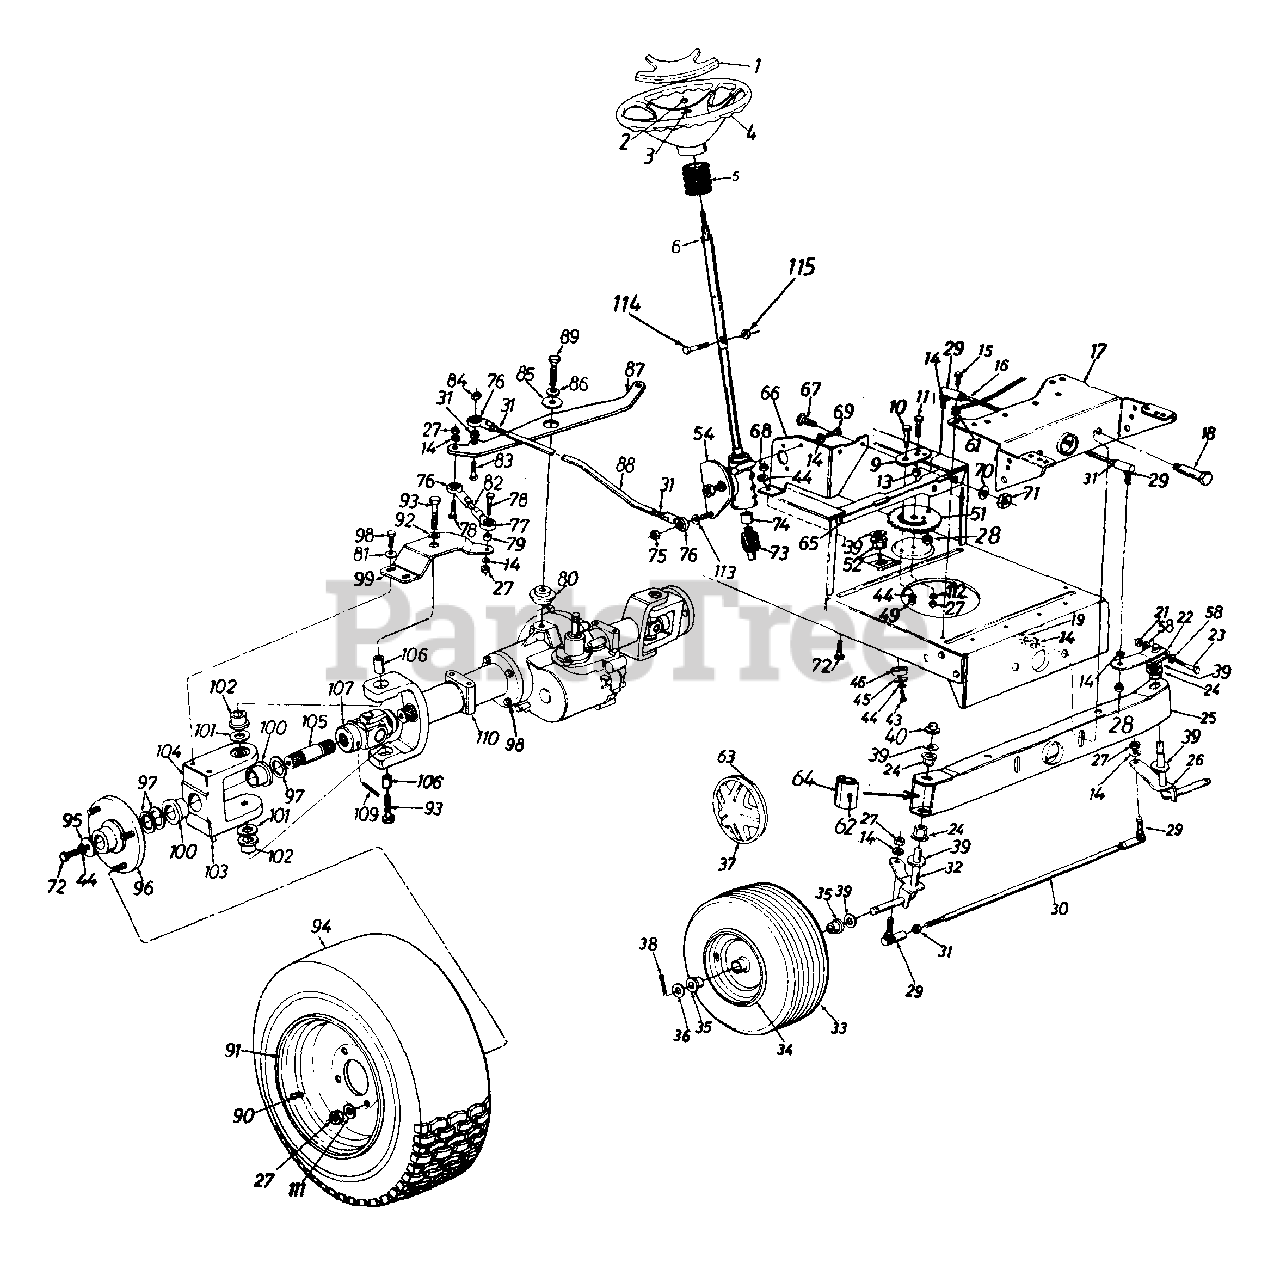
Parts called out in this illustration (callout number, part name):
1	Steering Wheel Cap
2	Hex L-Nut 5/16-24 Thd.
3	Belleville Wash. .345" I.D.
4	Steering Wheel
5	Steering Bellow
6	Upper Steering Shaft
9	Retainer Plate
10	Shoulder Bolt .437" Dia. x .35" Lg. 5/16-18 Thd.
11	Hex Bolt 3/8-24 x 1.0" Lg. (Grade 5)
13	Spacer .380" I.D. x .625" O.D. x .227"
14	L-Wash. 3/8" I.D.
15	Hex Wash. Hd. Self-Tap Scr.
16	Steering Drag Link
18	Shoulder Bolt .498" Dia. x 2.04" Lg. 3/8-16 Thd.
19	Flanged L-Nut 3/8-16 Thd.
21	Hex Cent. L-Nut 5/16-24 Thd.
22	Steering Arm Front Axle
23	Hex Bolt 5/16-24 x 2.00" Lg. (Grade 5)
24	Hex Flg. Brg. .634" I.D.
26	Front Axle Ass'y. - L.H.
27	Hex Nut 3/8-24 Thd.
28	Hex Jam Nut 3/8-24 Thd.
29	Ball Joint 3/8-24 Thd.
31	Hex Jam Nut 3/8-24 Thd.
32	Front Axle Ass'y. - R.H.
35	Ball Bearing
36	Fl-Wash. .635" I.D. x 1.59" O.D.
37	Front Hub Cap
38	Cotter Pin 1/8" Dia. x 1.25" Lg.
39	Fl-Wash. .640" I.D. x .24" O.D.
43	Hex L-Bolt 5/16-18 x .62"
44	L-Wash. 5/16" I.D.
45	Fl-Wash. .33" I.D. x 1.25" O.D.
46	Spacer (Plastic)
49	Hex L-Nut 5/16-18 Thd.
51	Steering Gear Segment
52	Hex Flg. Brg. .634 I.D.
54	Steering Box Ass'y. Comp.
58	Wave Wash. .32" I.D. x .62"
61	Ext. L-Wash. 5/16" I.D.
62	Grease Fitting
63	Spring Clip
64	Pivot Bar End Cap
65	Horizontal Cross Bracket
66	Vertical Mounting Bracket
67	Hex Bolt 1/4-28 x .75" Lg.
68	Hex Nut 5/16-24 Thd.
69	Hex Bolt 3/8-16 x 1.0" Lg.
70	Bell-Wash. .265" I.D. x .75"
71	Hex Nut 1/4-28 Thd.
72	Hex Bolt 5/16-24 x .75" Lg.
73	Pinion Shaft
74	Steering Shaft Splined Coupler
75	Hex L-Nut 3/8-24 Thd.
76	Rod End 3/8-24 Thd. - R.H.
77	Rod End 3/8-24 Thd. - L.H.
78	Hex Bolt 3/8-24 x 1.5" Lg. (Gr. 5)
79	Spacer .38" I.D. x .625"
80	Shld. Spacer .51" I.D.
81	Bell-Wash. .38" I.D. x .88"
83	Hex Bolt 3/8-24 x 1.25" Lg.
84	Hex Patch L-Nut 3/8-24 Thd.
85	Fl-Wash. .531" I.D. x 1.75"
86	Bell-Wash. .505" I.D. x 1.0"
89	Hex Bolt 1/2-13 x 1.5" Lg. (Gr. 5)
90	Air Valve
93	Hex Bolt 1/2-20 x 1.75" Lg. (Gr. 5)
95	Fl-Wash. .33" I.D. x 1.25"
96	Wheel Flange Ass'y.
97	Fl-Wash. 1.0" x 1.56"
98	Hex Bolt 3/8-24 x 1.25" Lg.
101	Fl-Wash. .76" I.D. x 1.5"
102	Flange Brg. 3/4" I.D.
103	Grease Fitting
104	Wheel Brg. Housing
106	Pivot Sleeve
109	Grooved Roll Pin 1.0" Lg.
110	Axle Horn Ass'y.
111	Bell-Wash. .38" I.D. x .88"
112	Bell-Wash. .39" I.D. x 1.38"
113	Fl-Wash. .385" I.D. x .62"
114	Hex Bolt 1/4-20 x 1.31" Lg.
115	Hex Ins. L-Nut 1/4-20 Thd.
